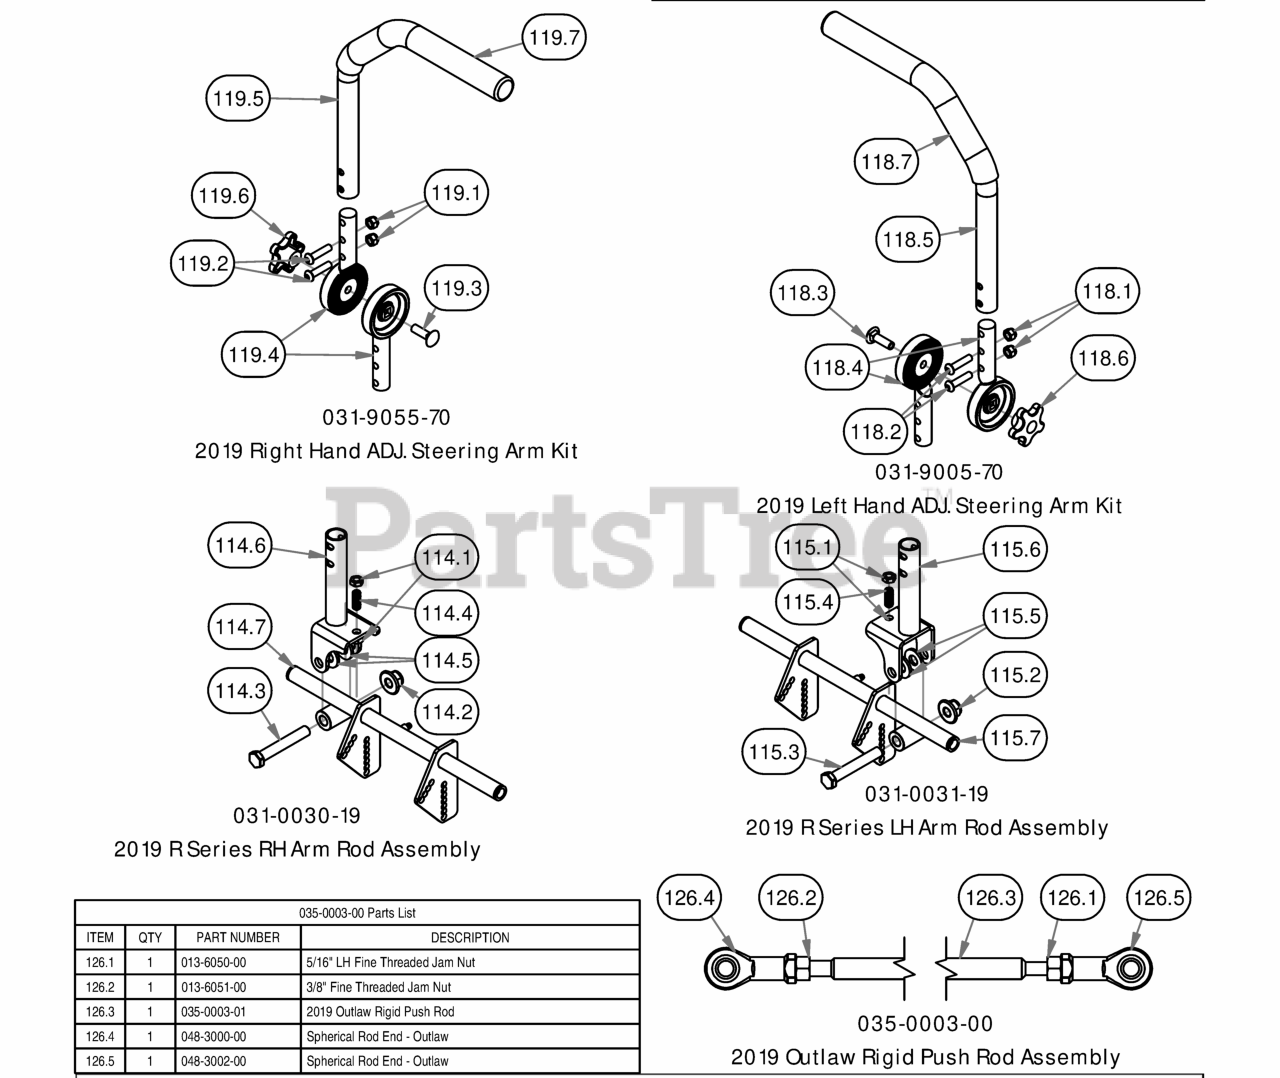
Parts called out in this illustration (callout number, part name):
114.1	3/8-16 Half Jam Nut
114.2	1/2-13 Nylon Flange Nut
114.3	1/2-13 x 3.25 GR 5 Hex Bolt Zinc
114.4	3/8-16 x 1 Set Socket Set Screw Cup Point
114.5	.505 Nylon Spacer
114.6	Drive Arm Pivot
114.7	2019 Drive Arm Actuator right
115.1	3/8-16 Half Jam Nut
115.2	1/2-13 Nylon Flange Nut
115.3	1/2-13 x 3.25 GR 5 Hex Bolt Zinc
115.4	3/8-16 x 1 Set Socket Set Screw Cup Point
115.5	.505 Nylon Spacer
115.6	Drive Arm Pivot
115.7	2019 Drive Arm Actuator left
118.1	5/16-18 Nylock Insert Locknut
118.2	5/16-18 UNC X 1-3/8" BHCS, TORX DRIVE, GR 5
118.3	3/8" x 1 1/4" Carriage Bolt
118.4	2019 Steering Arm Adjuster Casting
118.5	2019 Steering Arm Grip
118.6	Black Knob for Adjustable Steering Arm
118.7	Black Steering Arm Grip
119.1	5/16-18 Nylock Insert Locknut
119.2	5/16-18 UNC X 1-3/8" BHCS, TORX DRIVE, GR 5
119.3	3/8" x 1 1/4" Carriage Bolt
119.4	2019 Steering Arm Adjuster Casting
119.5	2019 Steering Arm Grip
119.6	Black Knob for Adjustable Steering Arm
119.7	Black Steering Arm Grip
126.1	5/16" LH Fine Threaded Jam Nut
126.2	3/8" Fine Threaded Jam Nut
126.3	2019 Outlaw Rigid Push Rod
126.4	Spherical Rod End - Outlaw
126.5	Spherical Rod End - Outlaw
